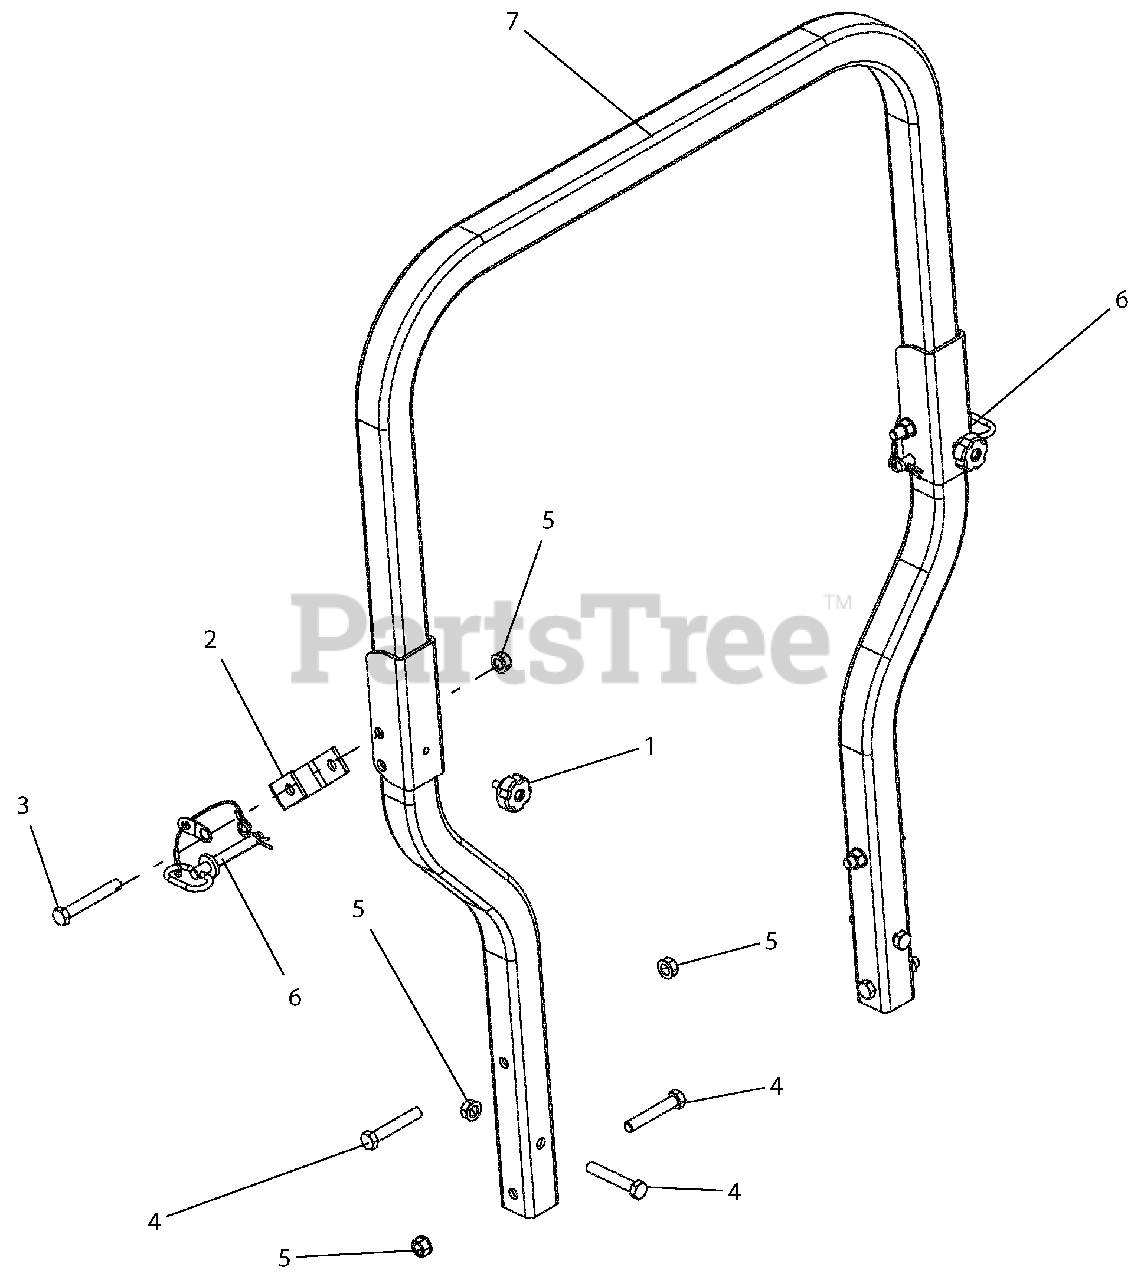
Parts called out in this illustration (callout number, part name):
1	KNOB, ROUND 5/16-18 X .750
2	BRKT, ROPS STOP
3	BLT-HEX .50-13X3.50 GR5 YWZC
4	BLT-HEX .50-13X3.00 GR5 YWZC
5	NUT, LK-TOP-FLG .50-13 YWZC
6	ASSY, ROPS PIN/LANYARD
7	ROPS, PT200 REPLACEMENT
